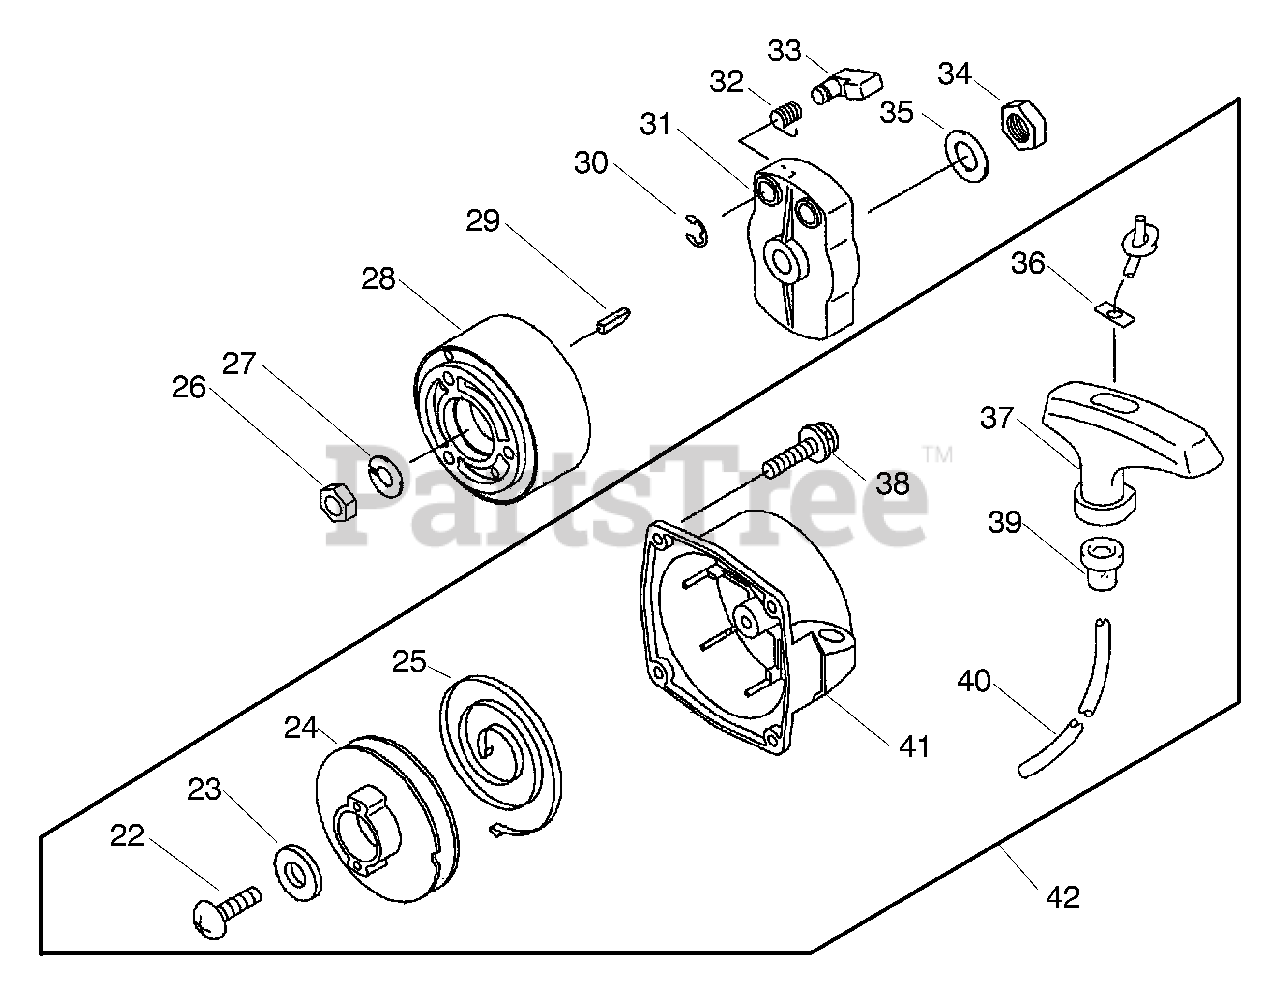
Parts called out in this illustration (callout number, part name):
24	Reel-Starter Recoil
25	Spring-Recoil
26	Nut-Hex (fine)
28	Flywheel
30	Ring-Snap
31	Pulley-Starting
32	Spring-Return
33	Pawl-Recoil Starter
34	Nut-Hex (fine)
35	W-Plain-S
36	Plate-Recoil Starter
37	Grip-Recoil Starter
39	Guide-Rope
40	Rope 3.8x850
41	Case-Recoil Starter
42	Starter-Recoil
